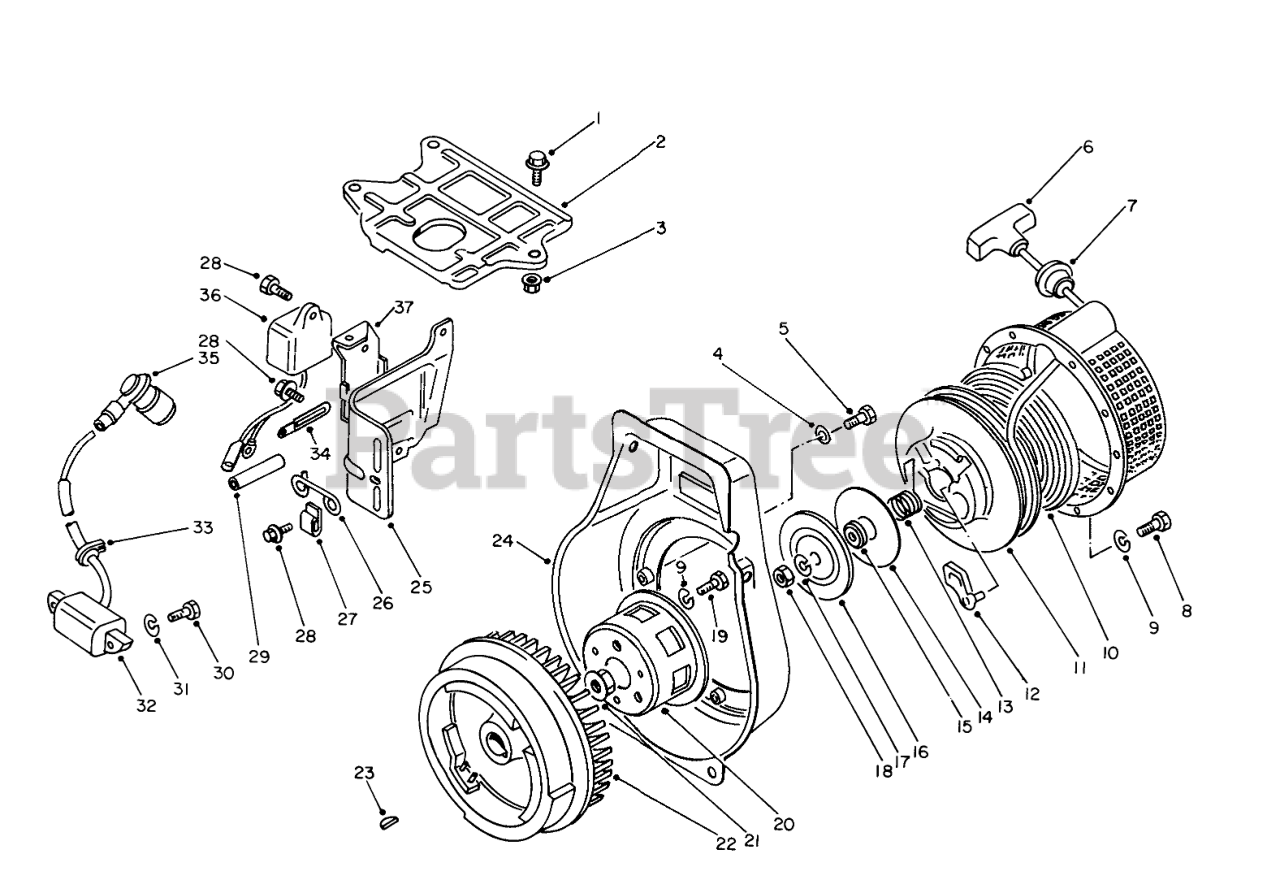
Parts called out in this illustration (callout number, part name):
2	Cowling-Upper
3	M6 X 1 LOCKNUT
4	Washer
5	Bolt
6	Grip
7	Grip Assembly (Incl. Ref. #6)
9	Lockwasher
10	SPRING
12	Ratchet
13	Spring
14	Plate-Slide
15	Cover
16	Plate
17	WASHER-LOCK
20	STARTER PULLEY
22	Rotor
24	Cover-Cooling Fan
25	Cowling-Side
26	Clamp
27	Clamp
29	CAP CONNECTOR
31	Washer-Lock
32	Stator
33	Grom met
34	Clamp
35	SPARK PLUG CAP
36	Unit-Transistor Magneto
37	Bracket
